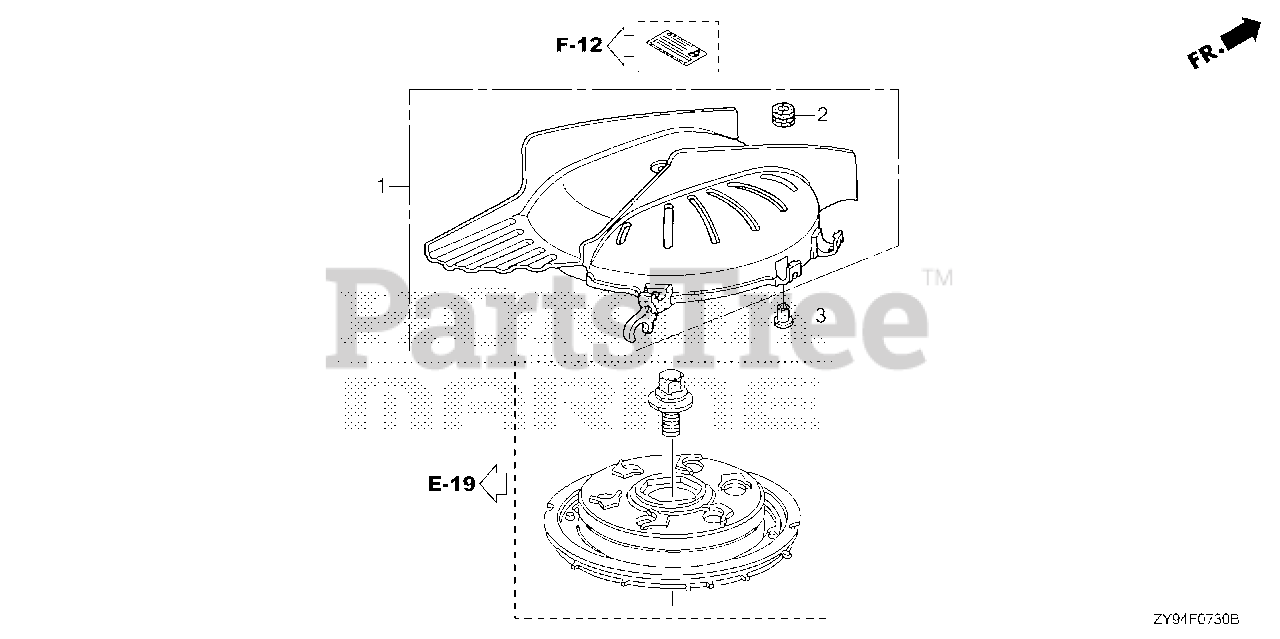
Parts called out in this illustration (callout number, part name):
1	COVER ASSY., ALTERNATOR
2	GROMMET, CASE (LOWER)
3	COLLAR, MODULE IGNITION CONTROL CASE (CDI)
